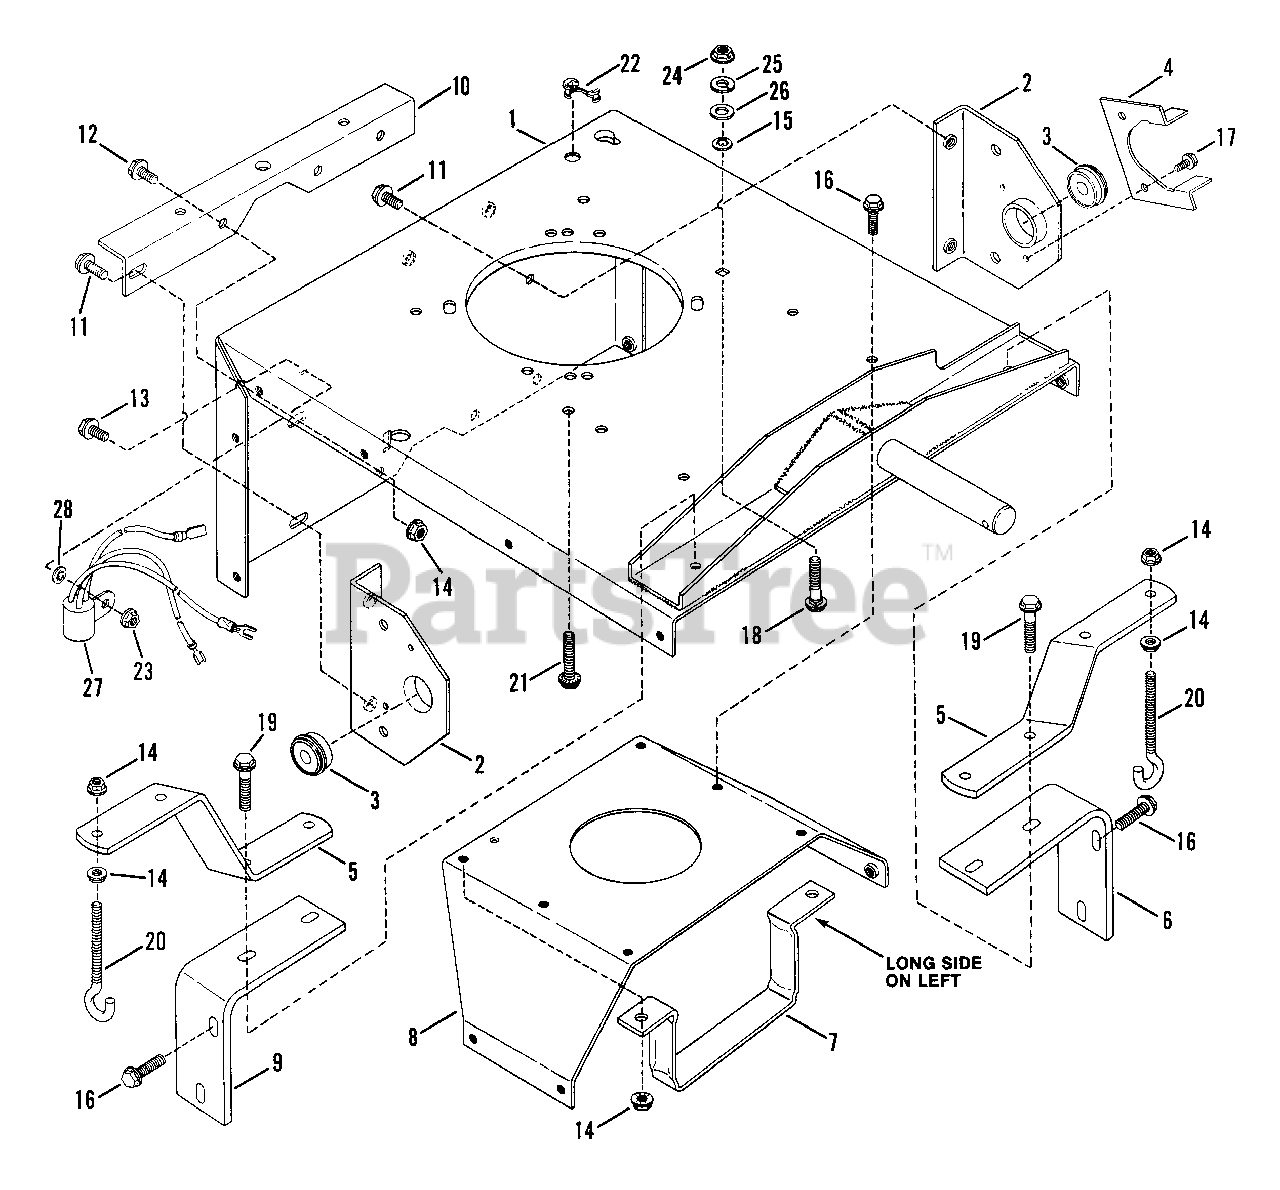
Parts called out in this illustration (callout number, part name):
1	FRAME, Rear
2	BRACKET, Support
3	BEARING
4	GUIDE, Belt
5	SUPPORT, Deck
6	STRAP, L. H.
7	GUIDE, Belt
8	SUPPORT, Deck
9	STRAP, R. H.
10	DRAW-BAR
11	SCREW, 5/16-18 x 5/8" ST
12	BOLT, 5/16-18 x 1/2" HFL
13	SCREW, 1/4-20 x 1/2" HWHST
14	NUT, 5/16-18 Hex Flange Lock
15	RETAINER, Bolt, 5/16"
16	SCREW, 5/16-18 x 3/4" ST
17	SCREW, 1/4-20 x 3/8" ST
18	BOLT, 5/16-18 x 1-1/2" SNC
19	SCREW, 5/16-18 x 1-1/2 HWHST
20	HOOK, Chain
21	BOLT, 5/16-18 x 1-1/2" HFL
22	STRAIN RELIEF
23	NUT, 1/4-20 HFL
24	NUT, 5/16-18 Hex
25	WASHER, 5/16 Split Lock
26	WASHER, 5/16 SAE
27	INTERLOCK, B & S
28	RETAINER, Bolt, 1/4"
